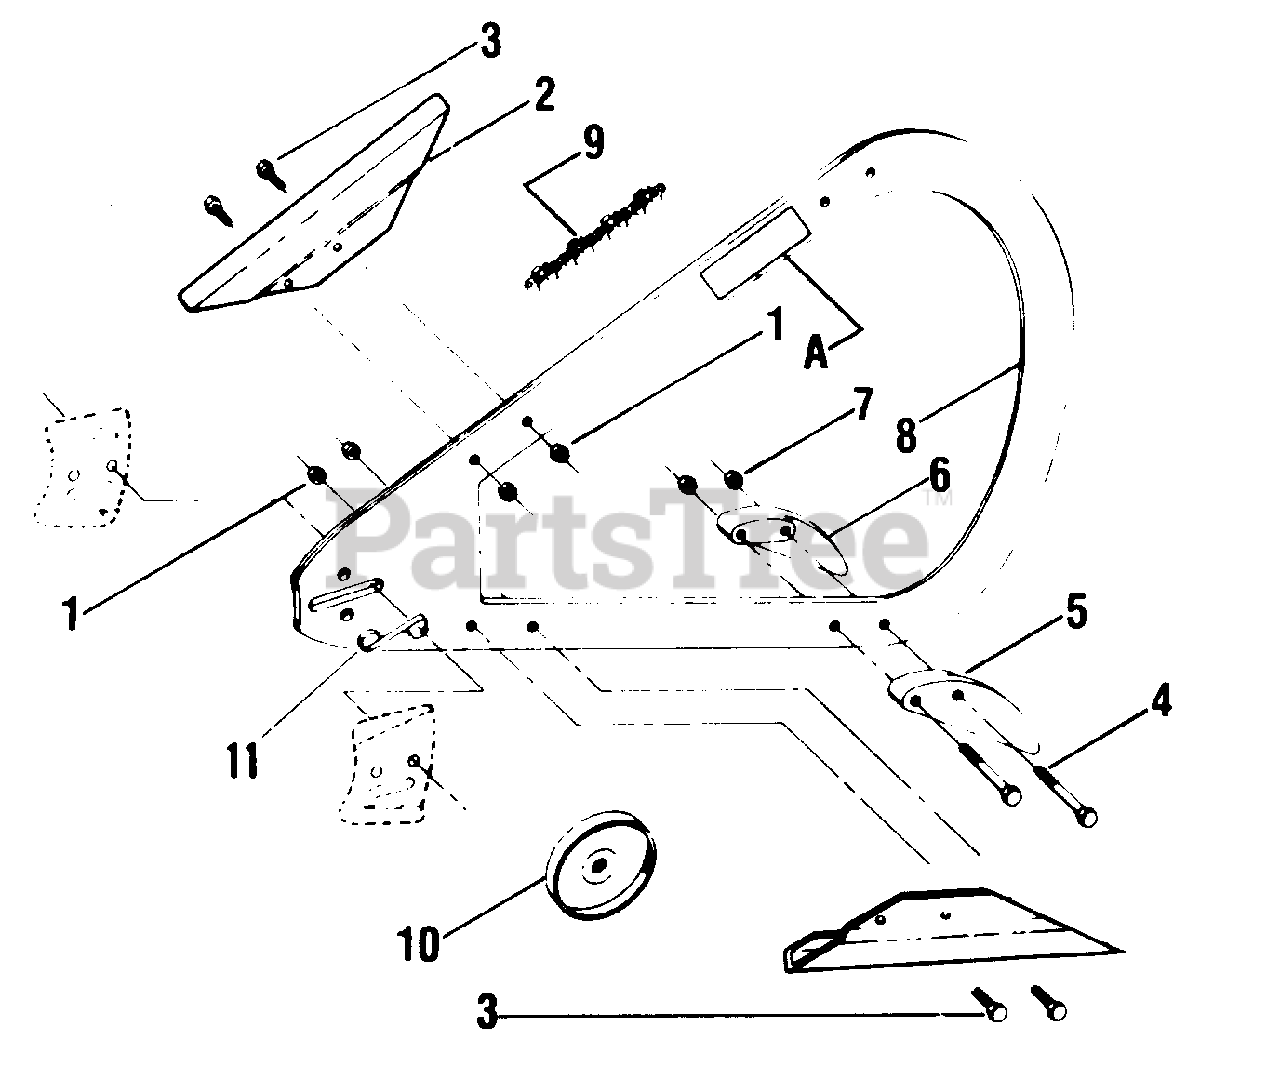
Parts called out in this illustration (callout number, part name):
1	Locknut - 12 - 24
2	Chain Guard - Upper & Lower
3	Screw - Guide Mtg. (12 - 24 x 5/8) Hex Head
4	Screw - Guard Mtg. (1/4 - 20 x 1-3/4 Hex Head)
5	Bumper Spike - Right
6	Bumper Spike - Left
7	Locknut - Bumper Spike Mtg. (1/4-20)
8	Bow Guide (See Bow & Chain Information)
9	Bow Guide (See Bow & Chain Information)
10	Drum and Sprocket Ass'y. (For .404 pitch only)
11	"S" Clip
A	Decal - Bow Guide Warning
